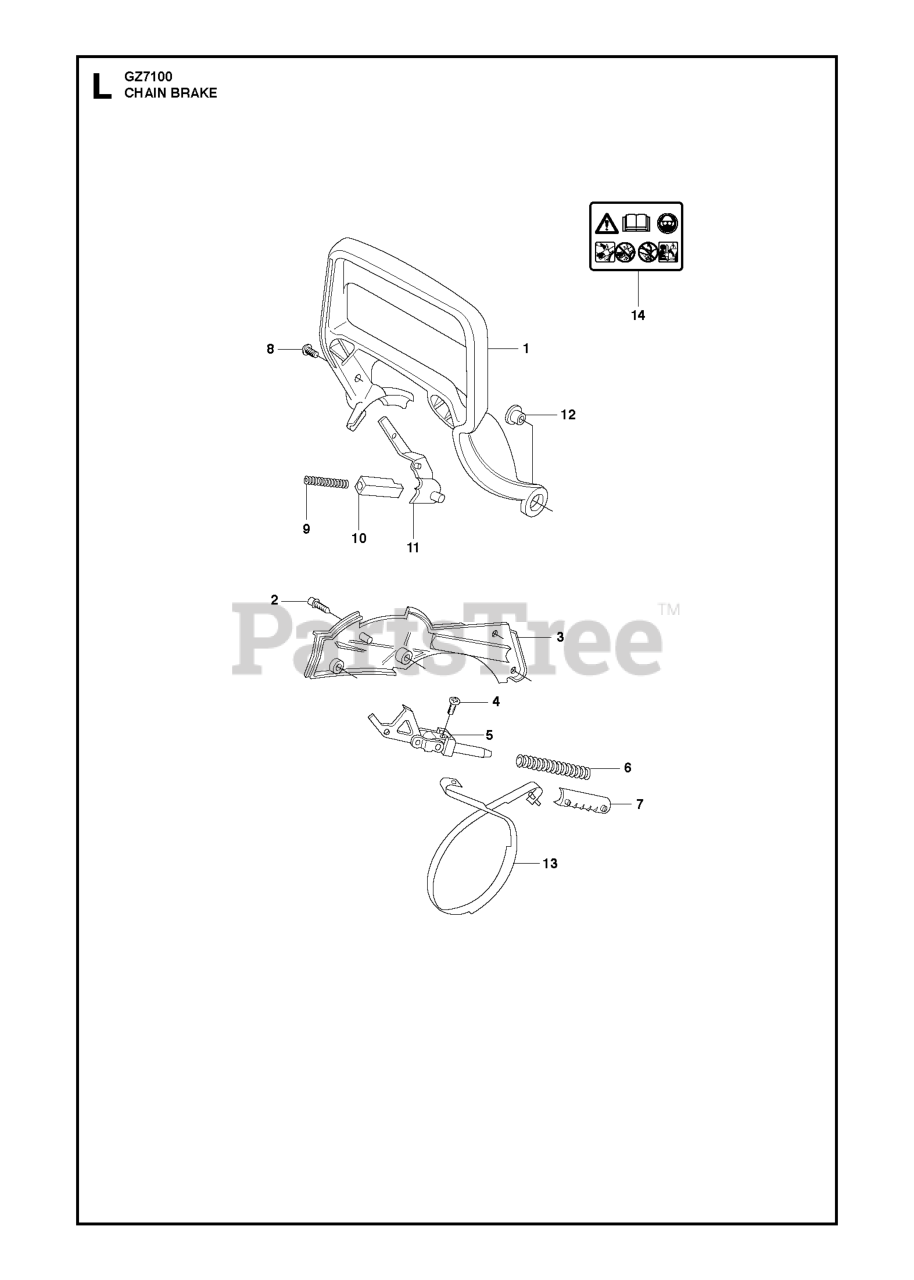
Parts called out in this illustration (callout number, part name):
1	HAND GUARD
2	SCREW ITXSCFM M5X12 T27 12.9
4	SCREW CITXPANT
5	KNEE LINK
6	BRAKE SPRING
8	SCREW ITXSCM M4X12 T27 12.9 T
9	LOCK SPRING
11	BRAKE LEVER
13	BRAKE BAND
14	DECAL
